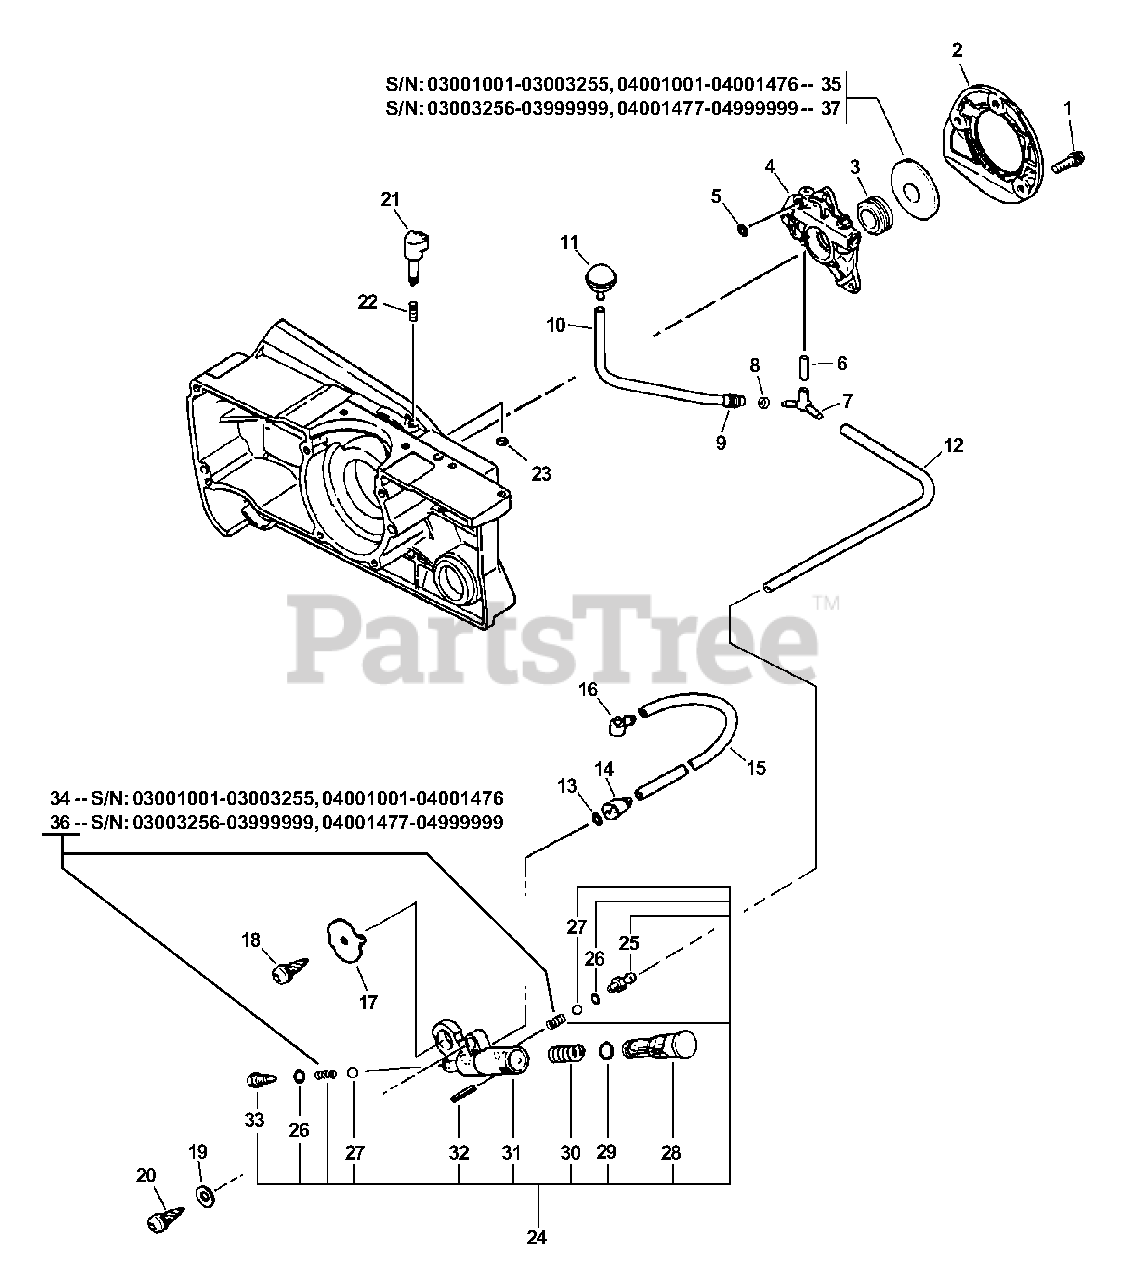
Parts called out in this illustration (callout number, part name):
1	SCREW - 4X12
2	COVER, OIL PUMP
3	GEAR - WORM
4	AUTO-OILER ASSY
5	O-RING - 3
6	PIPE - 3X6X20 -- BLACK
7	CONNECTOR, PIPE
8	CLIP - 6.5
10	PIPE - OIL
11	FILTER, OIL
12	PIPE - 3X6X200 -- BLACK
13	O-RING - 3
14	CONNECTOR, PIPE
15	PIPE, OIL - 3X6X125
16	CONNECTOR, PIPE
17	BRACKET, OIL PUMP
18	SCREW - 4X10
19	WASHER - 5
20	SCREW - 5X20
21	DIAL, AUTO-OILER
23	RING, RETAINING - 3
24	OIL PUMP ASSY
27	VALVE, BALL
28	PISTON, OIL PUMP
29	O-RING - 7
31	BODY, OIL PUMP
32	PIN - SPRING -- 2X16
33	ADAPTER, OIL PUMP
34	SPRING, VALVE
35	WASHER - 12
37	WASHER - 12
